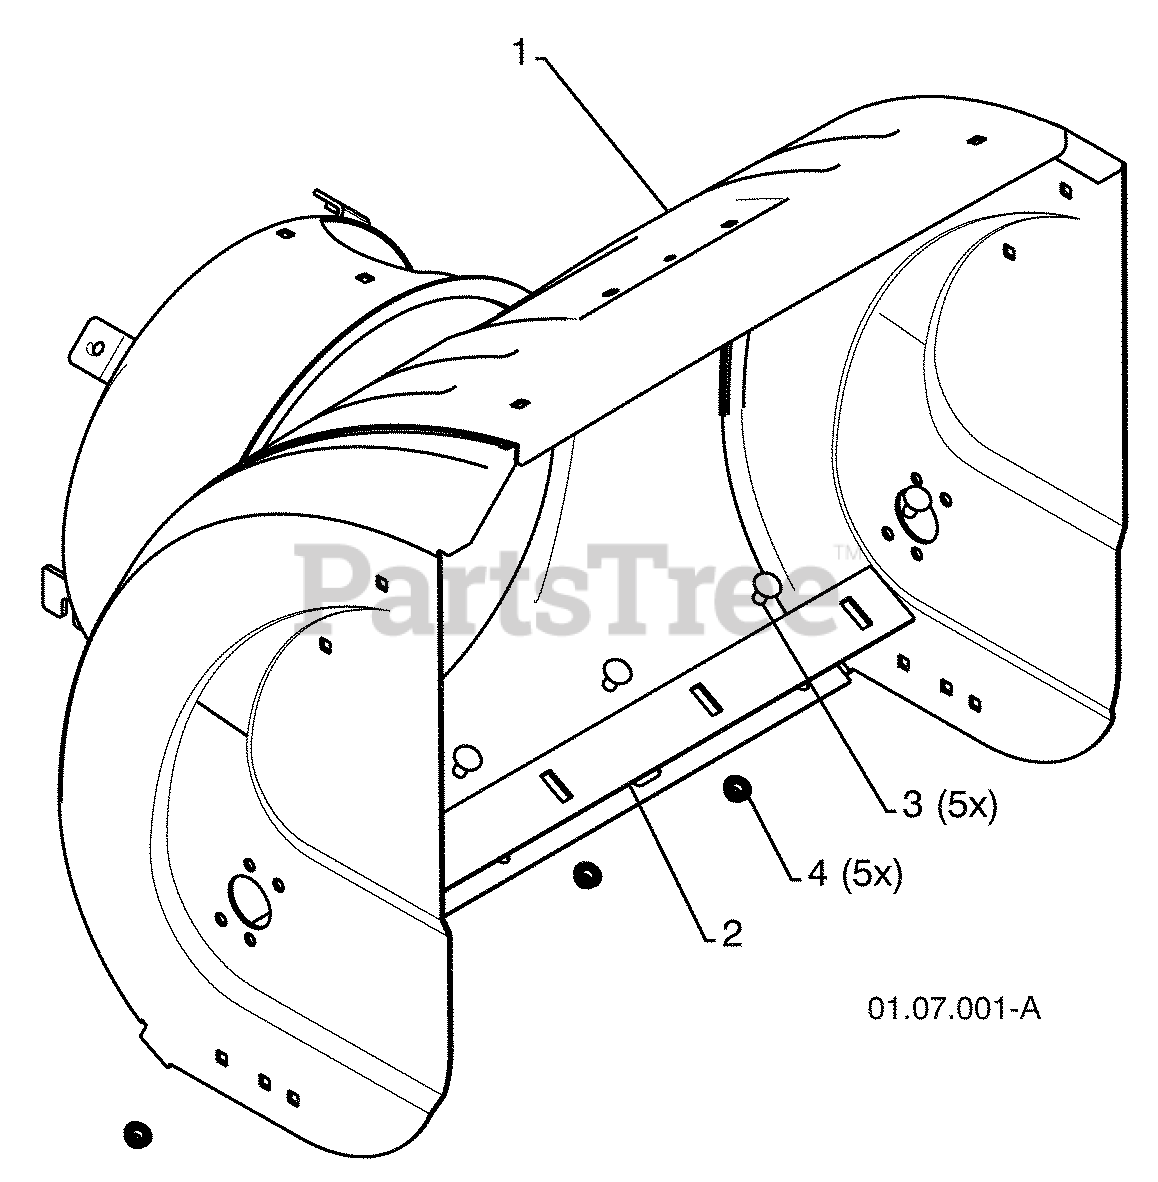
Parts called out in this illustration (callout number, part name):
1	AUGER HOUSING
2	SCRAPPER BAR
3	CARRIAGE BOLT 5/16--18 X .625
4	NUT 5/16--18
